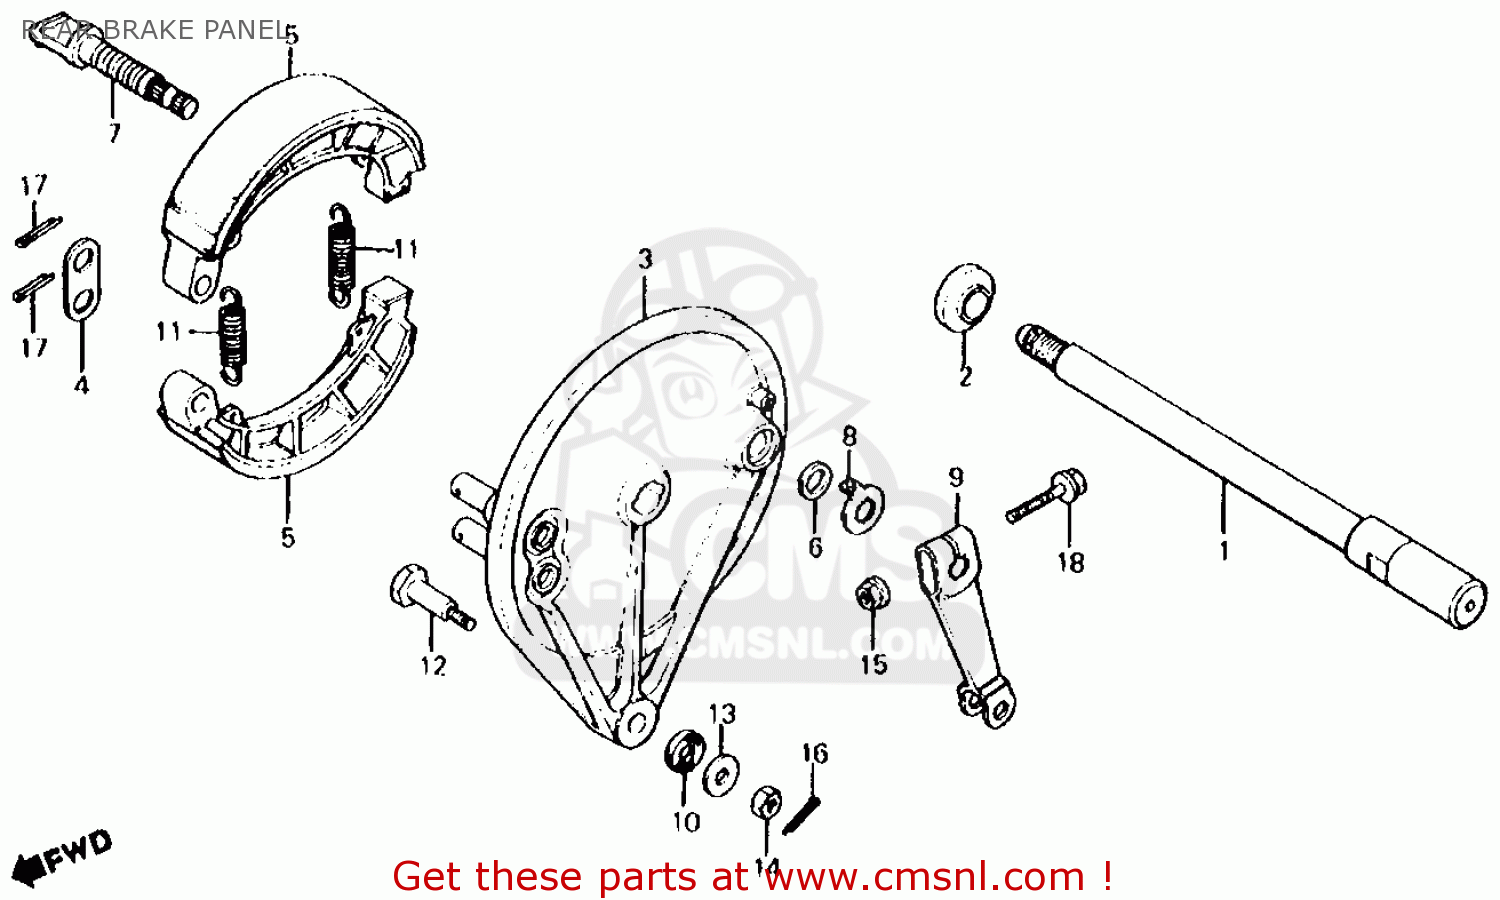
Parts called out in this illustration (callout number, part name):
1	AXLE,RR.WHEEL
2	COLLAR,PANEL SIDE
3	PANEL COMP.,RR.
4	WASHER BRAKE PIN
5	SHOE COMP.,RR.BRA (NAS)
6	SEAL BRAKE CAM
7	CAM,RR.BRAKE
8	INDICATOR,BRAKE
9	ARM,RR BRAKE
10	RUBBER CUSHION
11	SPRING,FR.BRAKE
12	BOLT,RR.BRAKE
13	WASHER,8MM
16	PIN,SPLIT, 2.0
17	PIN COTTER 2.5MM
18	BOLT,FLANG,8X40
